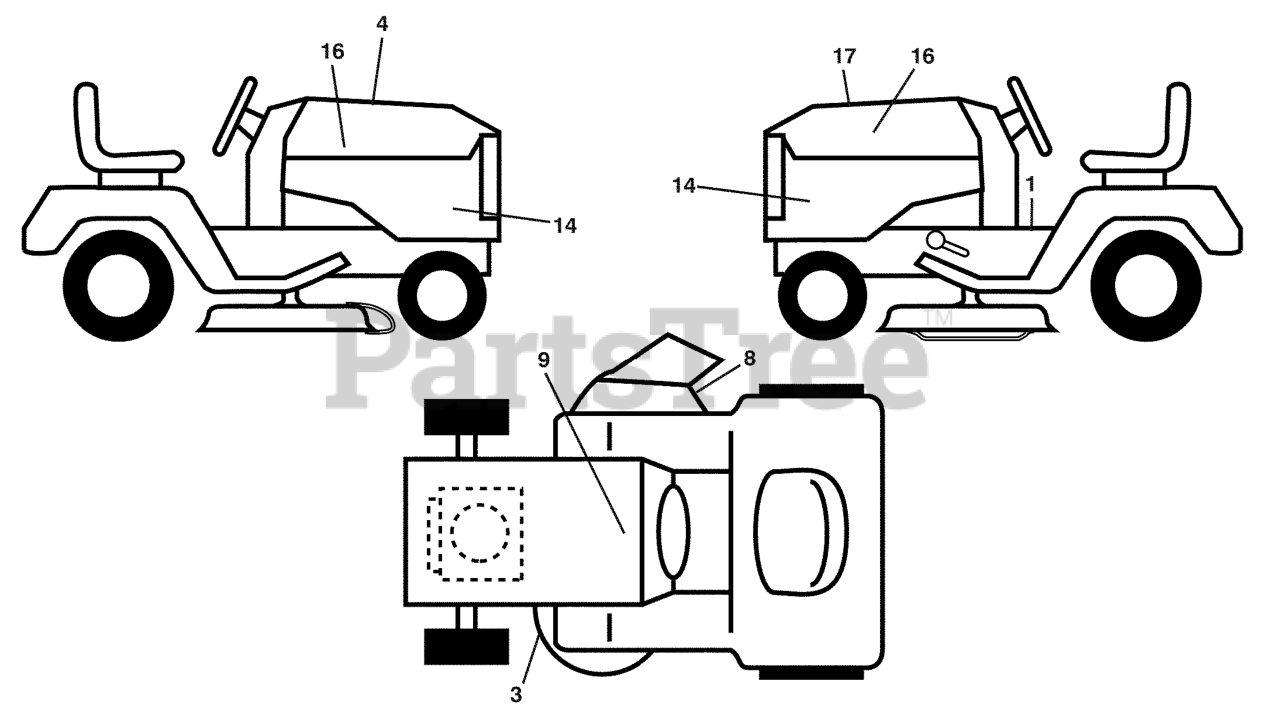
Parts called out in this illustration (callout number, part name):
1	DECAL.FENDER.WARNING.ENG
3	DECAL.WARN.KEEP.HAND.AWAY
4	DECAL.WARNING.CUST.RESP.E85.
8	DECAL.MOWER.SCH.48/54
9	DECAL BTRY SYMBOLS
14	DECAL.PNL.SD.LGT2554.KOHL.
16	RP EMBLEM, HOOD
